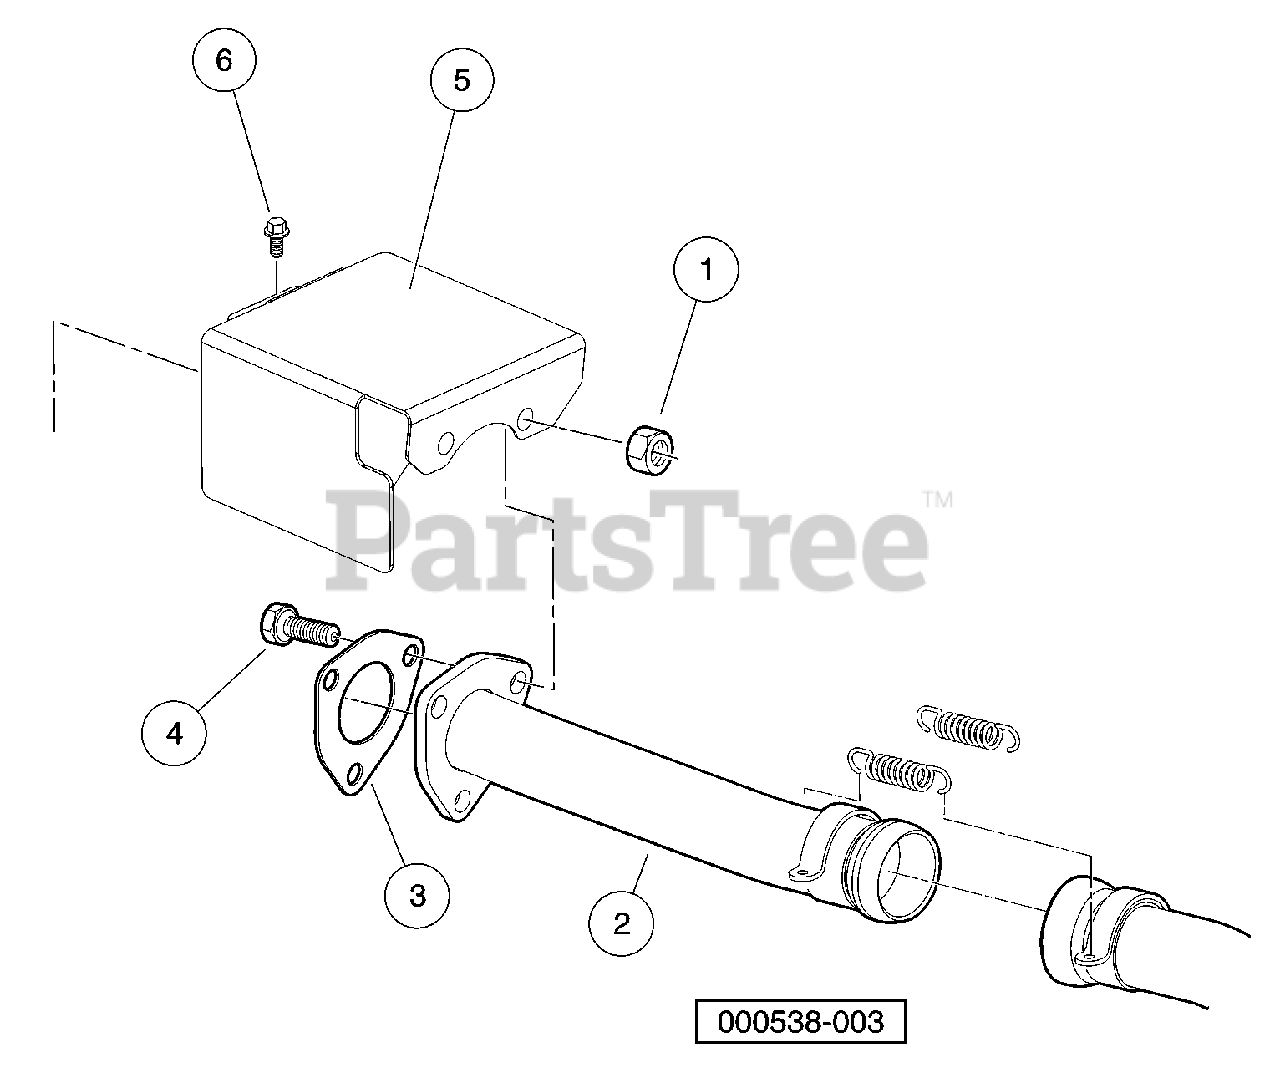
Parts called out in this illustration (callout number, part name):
1	Nut,m8,all Metal Lock
2	Pipe, Exhaust Diesel Main
3	Gasket, Exhaust Diesel
4	Bolt, M8 X 1.25 X 40 with Loctite
5	Shield, Diesel Exhaust.
6	Bolt, D722, Exhst Manfld Cover
